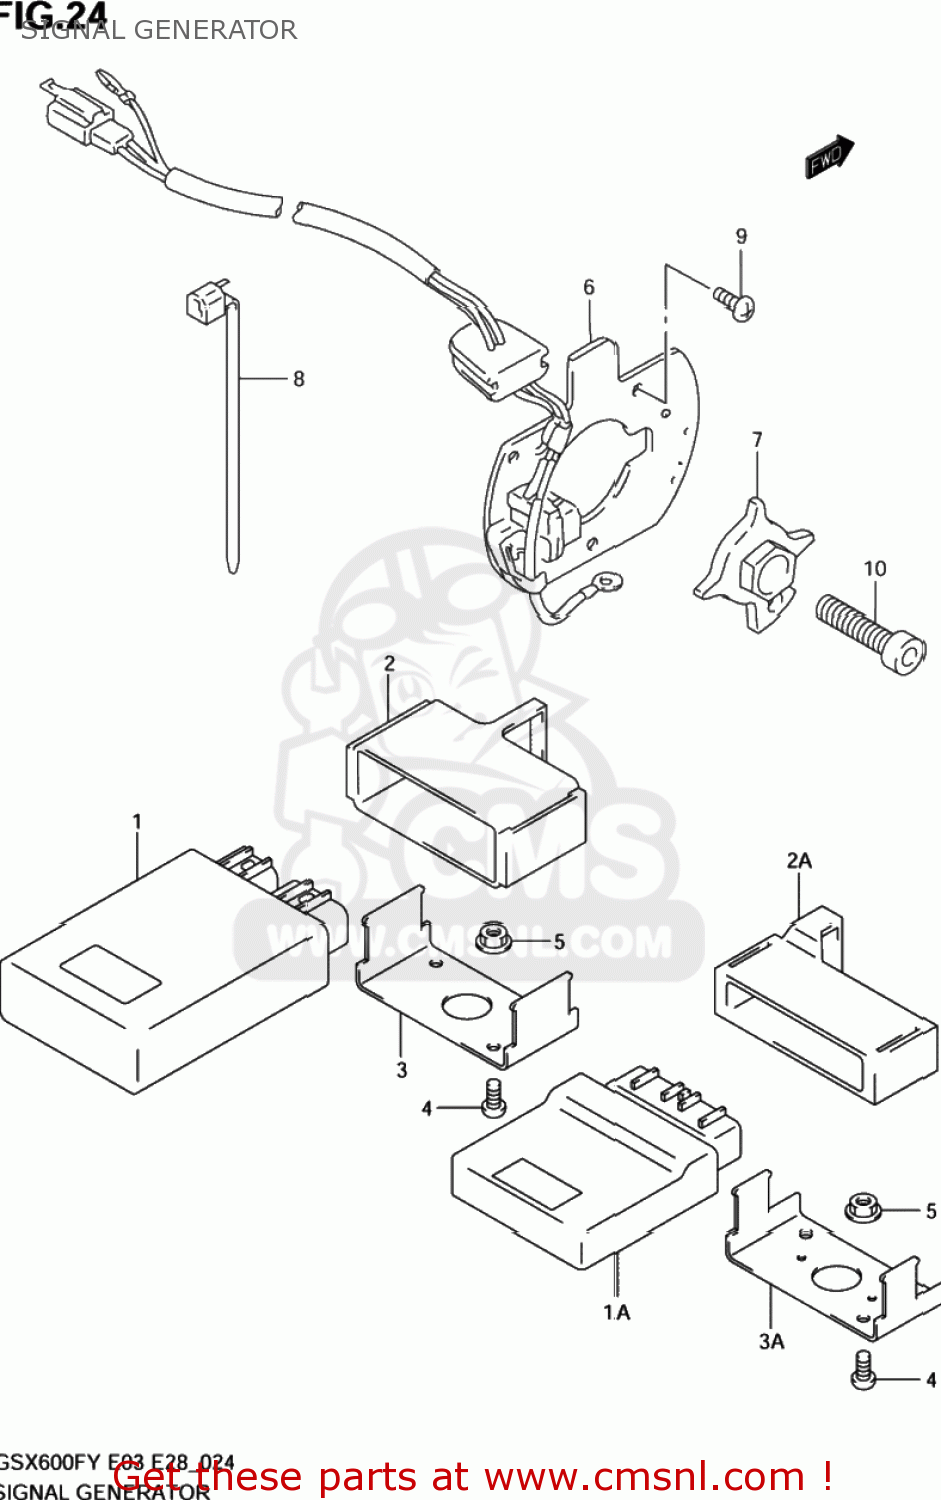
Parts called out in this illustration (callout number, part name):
1	IGNITOR ASSY
1A	IGNITER ASSY
2	CUSHION,IGNITOR
2A	COVER,IGNITOR
3	BRACKET,IGNITOR
3A	BRACKET,IGNITOR
4	SCREW 5X12
5	NUT
6	GENERATOR ASSY,SIGNAL
7	ROTOR,SIGNAL GENERATOR
8	CLAMP(L:125)
9	SCREW
10	BOLT
